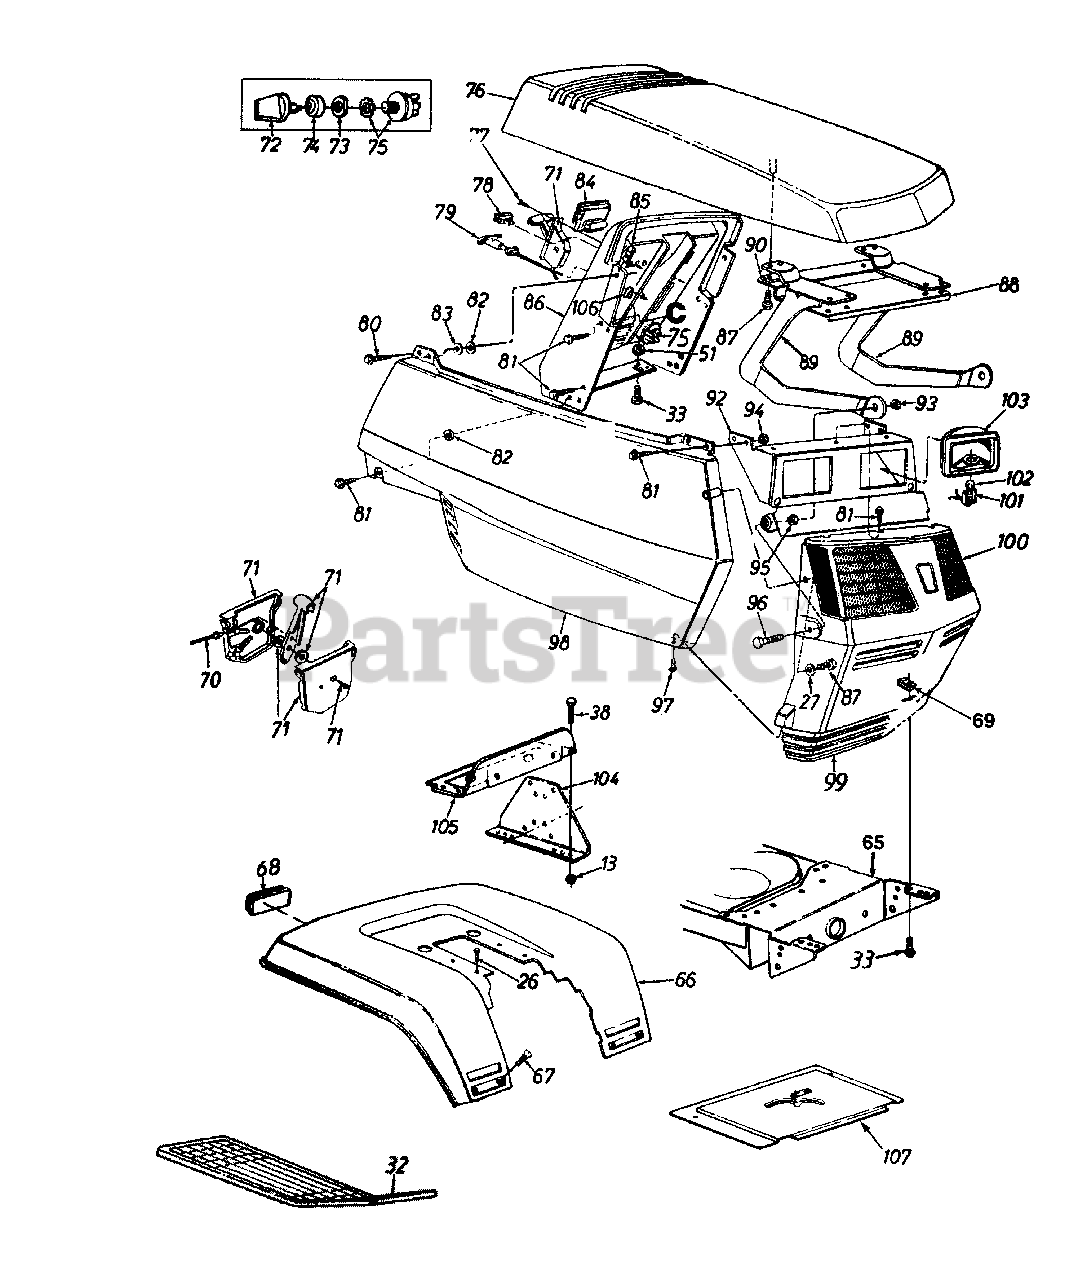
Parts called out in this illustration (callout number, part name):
26	Hex Wash. Hd. AB-Tap Scr. 5/16 x .75" Lg.
27	Fl-Wash. .218" I.D. x .5" O.D.
32	Rubber Foot Pad L.H.
33	Hex Bolt 5/16-18 x .75" Lg.
38	Hex Bolt 1/4-20 x .62" Lg.
51	Hex Sems Nut 5/16-18 Thd.
68	Reflector
69	U-Nut 5/16-18 Thd.
70	Throttle Wire 18.5" Lg.
71	Throttle Control Box Ass'y.
72	Ignition Key
73	Ignition Switch Nut
74	Ignition Switch Cap
75	Ignition Switch
76	Hood
77	Truss Mach. AB-Tap Scr. #10 x .5" Lg.
78	Light Switch
79	Choke Control 29" Lg.
80	Hex Wash. Hd. Tap Scr. 1/4 x .75" Lg.
81	Hex Tap Scr. 1/4-20 x .5" Lg.
82	Push Nut Fastener
83	Fl-Wash. .27" I.D. x .948"
84	Ammeter
85	Speed Nut 1/4-20 Thd.
86	Dash Panel
87	Hex Wash. Hd. B-Tap Scr. 1/4 x .75" Lg.
94	Hex L-Nut 1/4-20 Thd.
95	Hex Jam Nut 5/16-18 Thd.
96	Hex Bolt 5/16-18 x 7/8" Lg.
97	Truss Mach. B-Tap Scr.#10 x .5" Lg.
98	Side Cover-R.H.
99	Grille
100	Lens-L.H.
101	Twist Lock-Lamp Socket
102	Lamp
103	Headlight Housing
